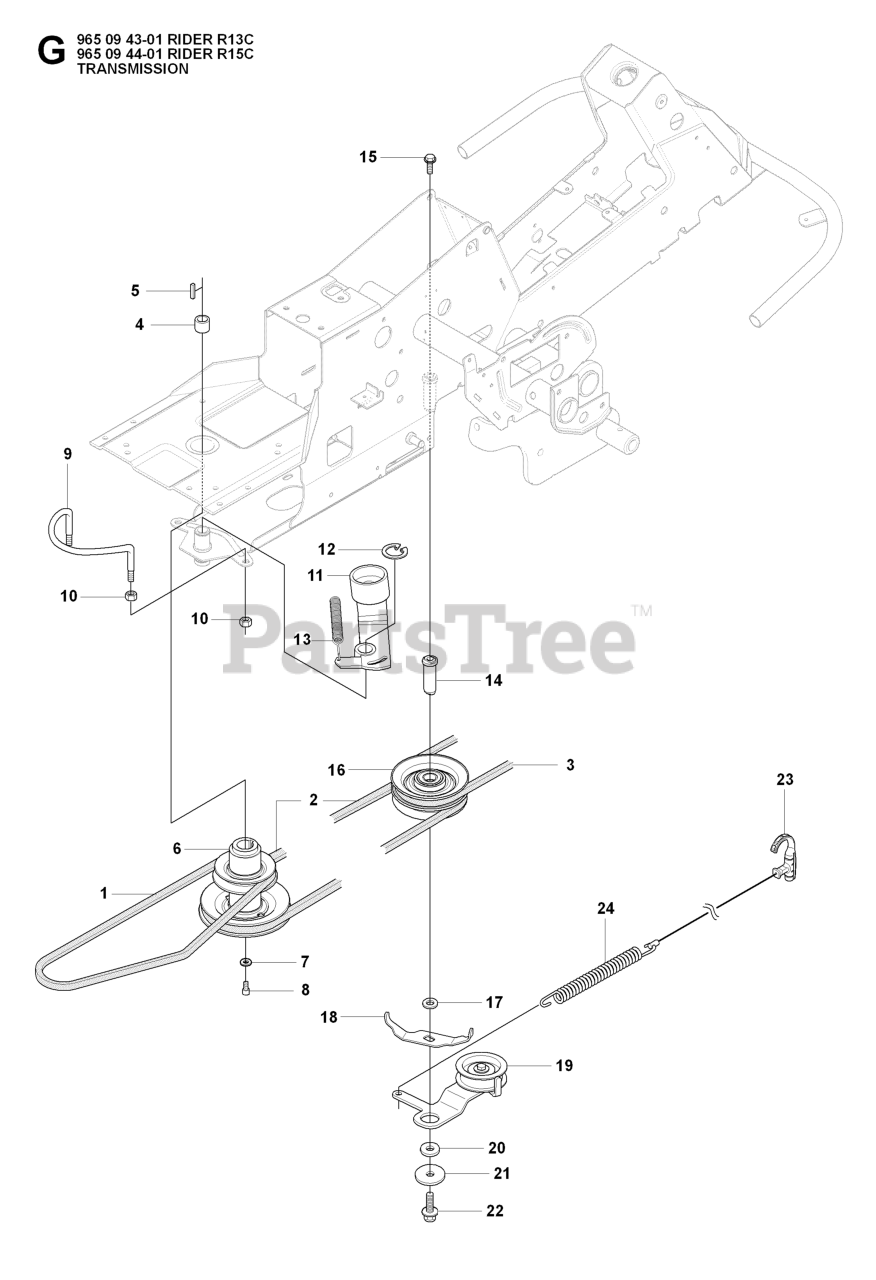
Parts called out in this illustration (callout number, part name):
1	BELT
2	BELT
3	BELT
9	BELT GUIDE
10	NUT
12	RETAINING RING SGA 25
14	SHAFT
18	BELT GUIDE
19	BELT TENSIONER ASSY
22	BOLT
